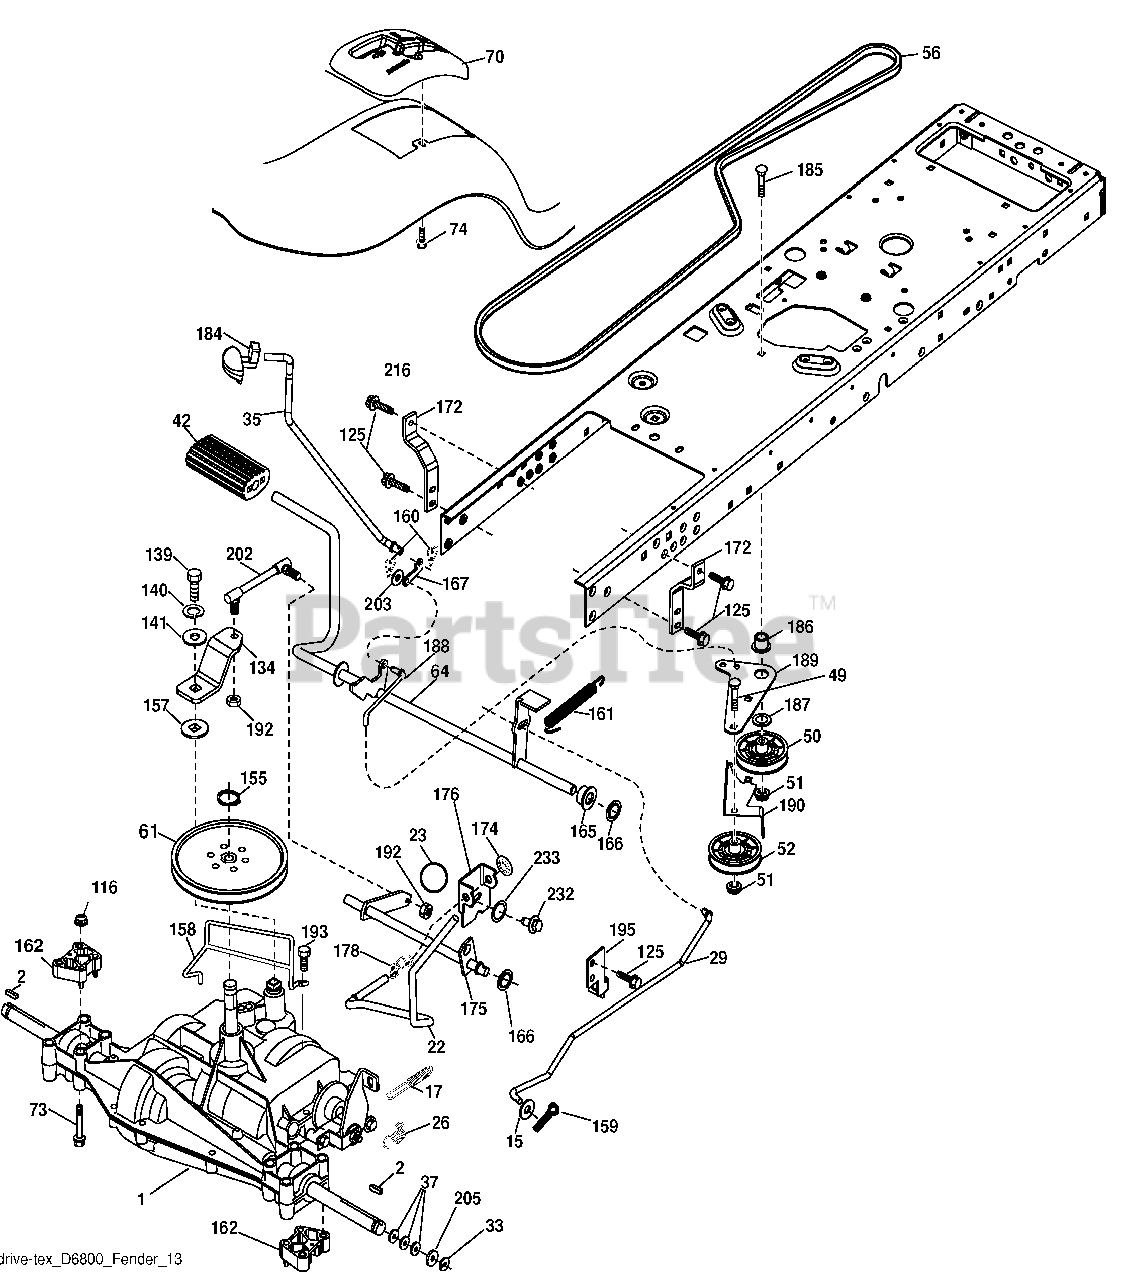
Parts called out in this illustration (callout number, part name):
1	Transaxle, D6800 (See Transaxle Breakdown)
2	Key Square
15	Washer 13/32 x 13/16 x 16 Ga.
17	Spring, Brake
22	Rod Shift
23	Knob
26	Spring Brake RTN
29	Rod, Brake
33	Ring E
35	Rod, Brake, Park
37	Washer 25/32 x 1-1/4 x 16 Ga.
42	Cover, Foot Pedal
49	Bolt
50	Pulley Idler Flat
51	Lock Nut 3/8-16
52	Idler V-Groove
56	V-Belt, Drive
61	Pulley Transaxle
64	Shaft Asm. Pedal Brake Control
70	Console
73	Bolt Hex FLNGD 5/16 - 18 x 3.75
74	Screw 1/4 x 1/2
116	Nut Lock Hex Flange 5/16-18
125	Screw 5/16-18 x 3/4
134	Arm Shift
139	Bolt 1/4-20 unf Gr. 8 w/Patch
140	Washer Lock Hvy Helical 1/4
141	Washer 9/32 x 3/4 x 10 Ga.
155	Ring Retainer
157	Washer Plate Shf
158	Keeper T/A
159	Pin Cotter 1/8 x 3/4
160	Retainer Clip
161	Spring, Return, Clutch
162	Spacer
165	Busing Shaft Brake Hand Control
166	Nut Push .625
167	Latch Brake Parking
172	Strap Torque LH
174	Nut Push
175	Shaft Asm Shift
176	Arm Clevis Rod Shift
178	Spring Shift
184	Handle Parking Brake
185	Bolt
186	Spacer Retainer
187	Washer
188	Link Clutch Ground Drive
189	Bellcrank Ground Drive
190	Keeper Bellcrank Ground Drive
192	Nut Lock Center 1/4-28
193	Screw 5/16-18 x 3/4
195	Bracket Brake Rod
202	Link Shift
203	Washer 11/32 x 11/16 x 16 Ga.
205	Washer 25/32 x 1-5/8 x 16 Ga.
232	Bolt 7/16-14 x 1 Gr.5
233	Washer Serrated
